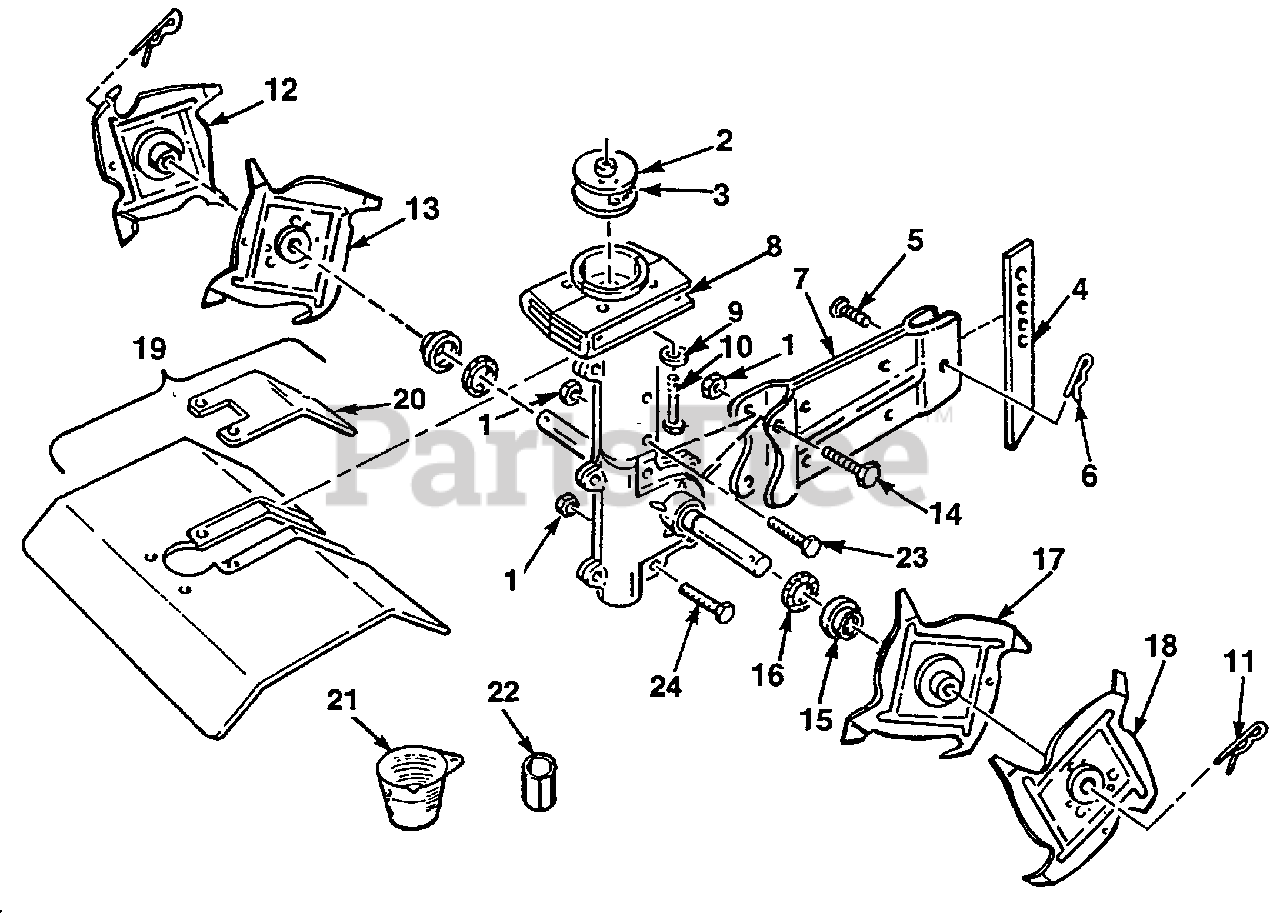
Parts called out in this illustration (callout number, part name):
1	NUT- 1/4-20
3	SPRING- Clutch
4	DRAG STAKE
5	PIN- Clevis, 5/16 x 7/8"
7	BRACKET ASSY.- Drag Stake
8	TRANSMISSION ASSY.
9	WASHER- Lock 1/4"
10	SCREW- 1/4-20 x 2", hex hd.
11	HAIRPIN- Cotter 3/4"
12	TINE AND HUB- R.H. Outboard (D)
13	TINE AND HUB- R.H. Inboard (C)
14	SCREW- 1/4-20 x 1"
15	DIRT CAP- Black Plastic
16	WASHER- Felt 1/8 x 3/4 x 1 1/2"
17	TINE AND HUB- L.H. Inboard (B)
18	TINE AND HUB- L.H. Outboard (A)
19	FRONT SHIELD
20	REAR SHIELD
21	FUEL MIX CUP (Generic)
22	TINE SPACERS
23	SCREW- Hex hd. 1/4-20 x 1 1/4"
24	SCREW- hex hd. 1/4-20 x 3/4"
